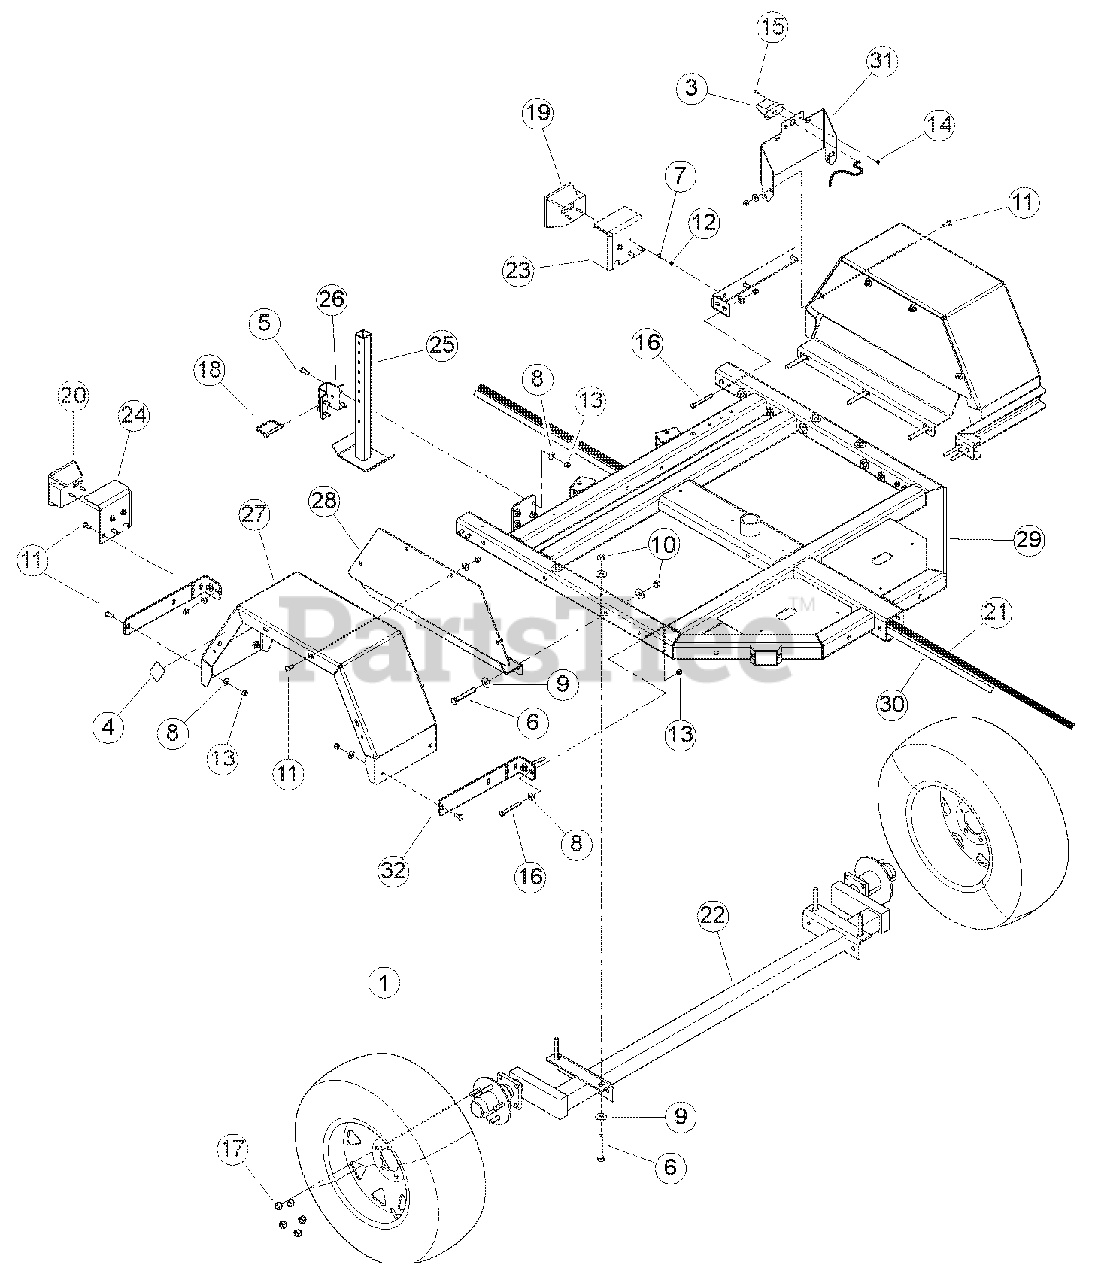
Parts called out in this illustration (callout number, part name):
1	ASSY, 15 INCH TIRE + WHEEL
2	PLUG, 12 VOLT LIGHT
3	LIGHT, LICENSE PLATE
4	REFLECTOR, WIDE ANGLE RED
5	BOLT, 3/8 X 1 HEX HD GR5 ZP
6	BOLT, 1/2"X3-1/2" GR5 HEXHD ZP
7	WASHER, 1/4" FLAT ZP(149PCS/LB)
8	WASHER, 3/8" FLAT ZP (67PCS/LB)
9	WASHER, 1/2" FLAT ZP-56PCS/LB
10	NUT, 1/2" CENTERLOCK GRB ZP
11	BOLT, CARR 3/8 * 1" GR5 NC ZP
12	NUT, 1/4" NE NYLOCK ZP
13	NUT, 3/8" NE NYLOCK ZP
14	NUT, 10/24 NYLOCK TYPE NM, ZP
15	SCW,MCH 10-24*1/2"PAN HD,PH ZP
16	BOLT, 3/8X3-1/4 HXHD GR5 ZP
17	NUT, 1/2-20 WHEEL
18	PIN, 3/8" X 2-3/4" SNAP
19	LIGHT, LH TAIL
20	LIGHT, RH TAIL
21	HARNESS, TRAILER LIGHT
22	AXLE, 2500 LB TORSION, WAS 18100-00 (SN 5VJAA0017BW002799 AND BELOW) (REPLACED AND SUPERSEDED. FOR SERVICE ORDER PN 31636-00, AXLE, TORSION SUSPENSION).
22	AXLE, TORSION SUSPENSION (SN 5VJAA0010BW002814 AND ABOVE)
23	BRACKET, LH TAILLIGHT
24	BRACKET, RH TAILLIGHT
25	WELDMENT, REAR STABILIZER
26	GUIDE, TRAILER SUPPORT
27	FENDER, CHIPPER
28	BRACKET, FENDER
29	WELDMENT, CHIPPER TRAILER
30	CONDUIT, 1/4 X 120 WIRE
31	BRACKET, LICENSE PLATE
32	ANGLE, FENDER GUSSET
